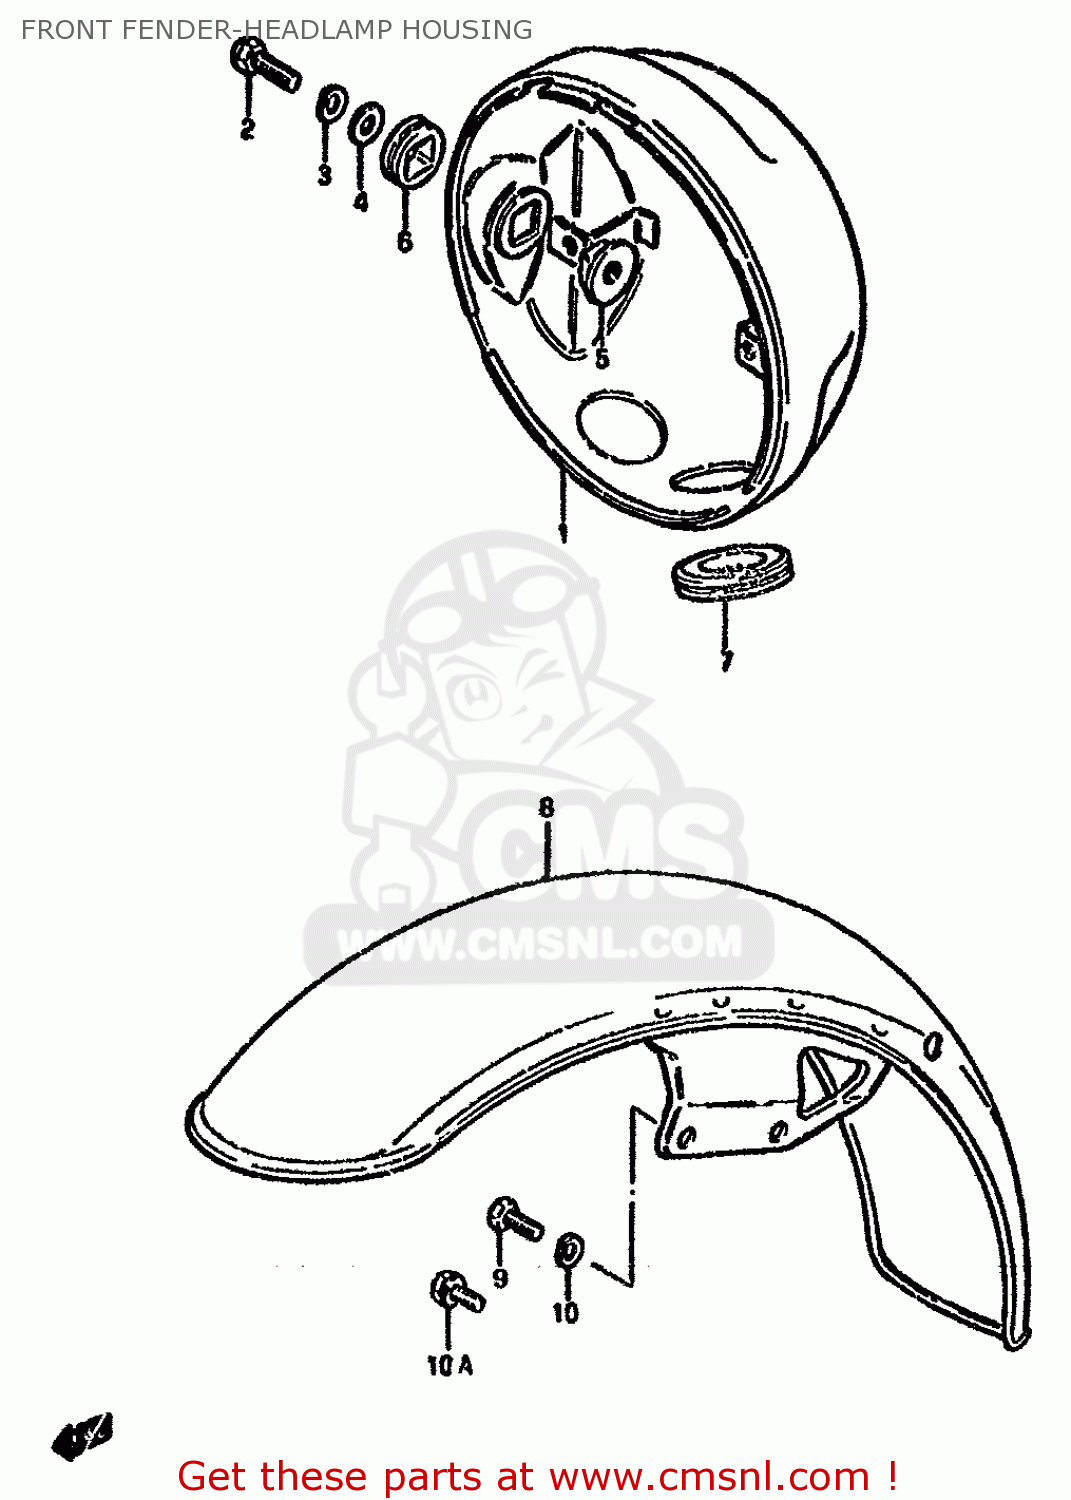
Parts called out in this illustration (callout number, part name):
1	HOUSING,HEADLAMP
2	BOLT
3	LOCK WASHER
4	WASHER
5	SPACER,HEADLAMP HOUSING
6	CUSHION,HEADLAMP HOUSING
7	GROMMET,HEADLAMP HOUSING
8	FENDER,FR
9	BOLT
10	LOCK WASHER
10A	BOLT, UPPER
